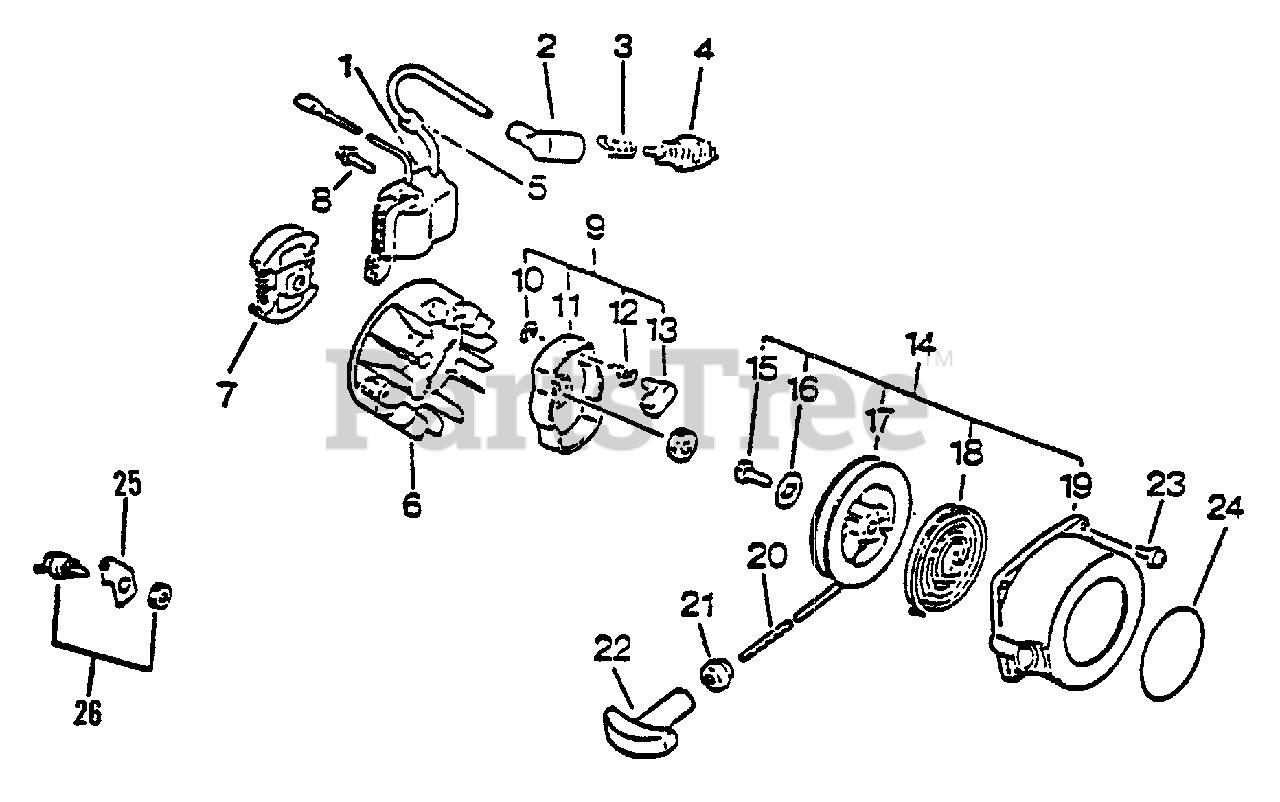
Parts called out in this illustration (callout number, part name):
1	COIL, IGNITION
2	CAP, SPARK PLUG
3	TERMINAL, SPARK PLUG
4	SPARK PLUG - BPM7A
4	SPARK PLUG - BPMR7A
6	FLYWHEEL
7	CLUTCH ASSY
8	SCREW 4×22
9	STARTER PAWL ASSY
10	E-RING 4
11	CATCHER, PAWL
12	SPRING, RETURN
13	PAWL, STARTER
14	STARTER ASSY
16	WASHER
17	REEL, ROPE
18	SPRING, RECOIL
19	CASE, RECOIL STARTER
20	ROPE, STARTER
21	GUIDE, ROPE
22	GRIP, STARTER
23	SCREW 4×16
24	LABEL, ECHO
25	SWITCH, ON-OFF
26	BRACKET, SWITCH
